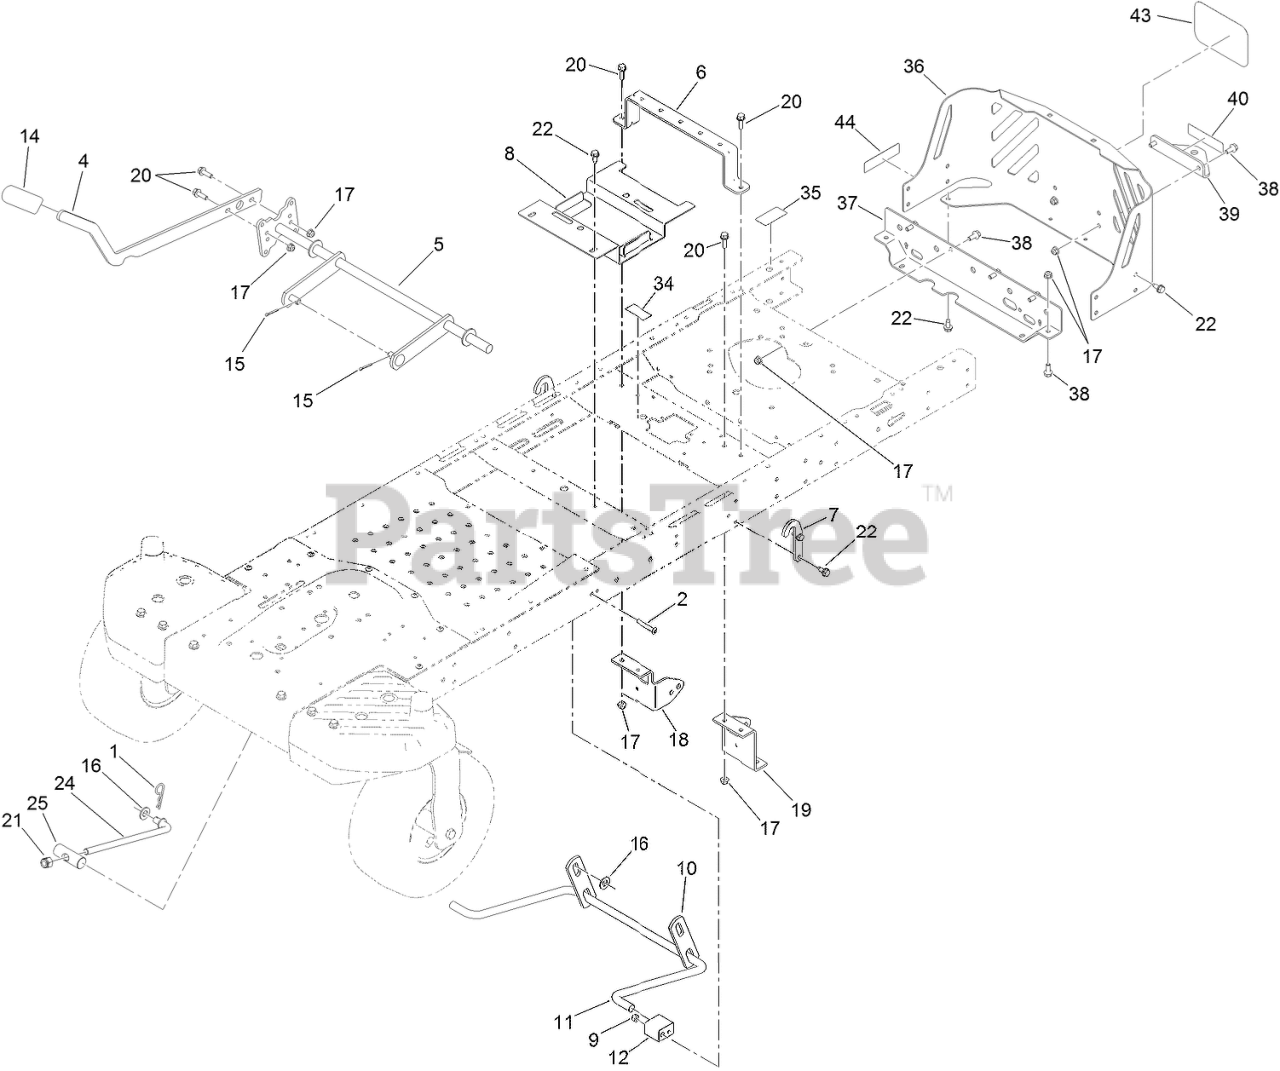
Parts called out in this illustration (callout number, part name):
1	PIN-COTTER
2	SCREW-HSBH
4	LEVER-LIFT
5	LIFT-DECK, NARROW
6	BRACE-SEAT, REAR (NARROW)
7	BRACKET-LIFT
8	BRACKET-BATTERY
9	NUT-LOCK, NI
10	LINK-LIFT
11	ARM-LIFT, REAR
12	BLOCK-PIVOT
14	GRIP-LEVER
15	PIN-COTTER
16	WASHER-FLAT
17	NUT-HF, NI
18	MOUNT-HYDRO, FRONT (RH)
19	MOUNT-HYDRO, FRONT (LH)
20	SCREW-HHF
21	NUT-HEX
22	SCREW-HWHTF
24	ROD-MOUNT, DECK
25	PIN-PIVOT
34	DECAL-LOCATION, SERVICE DEALER
35	DECAL-BYPASS
36	GUARD-ENGINE, NARROW
37	CROSSMEMBER-REAR, NARROW
38	SCREW-HHF
39	BRACKET-HITCH
43	DECAL
44	DECAL-ARRESTER, SPARK
